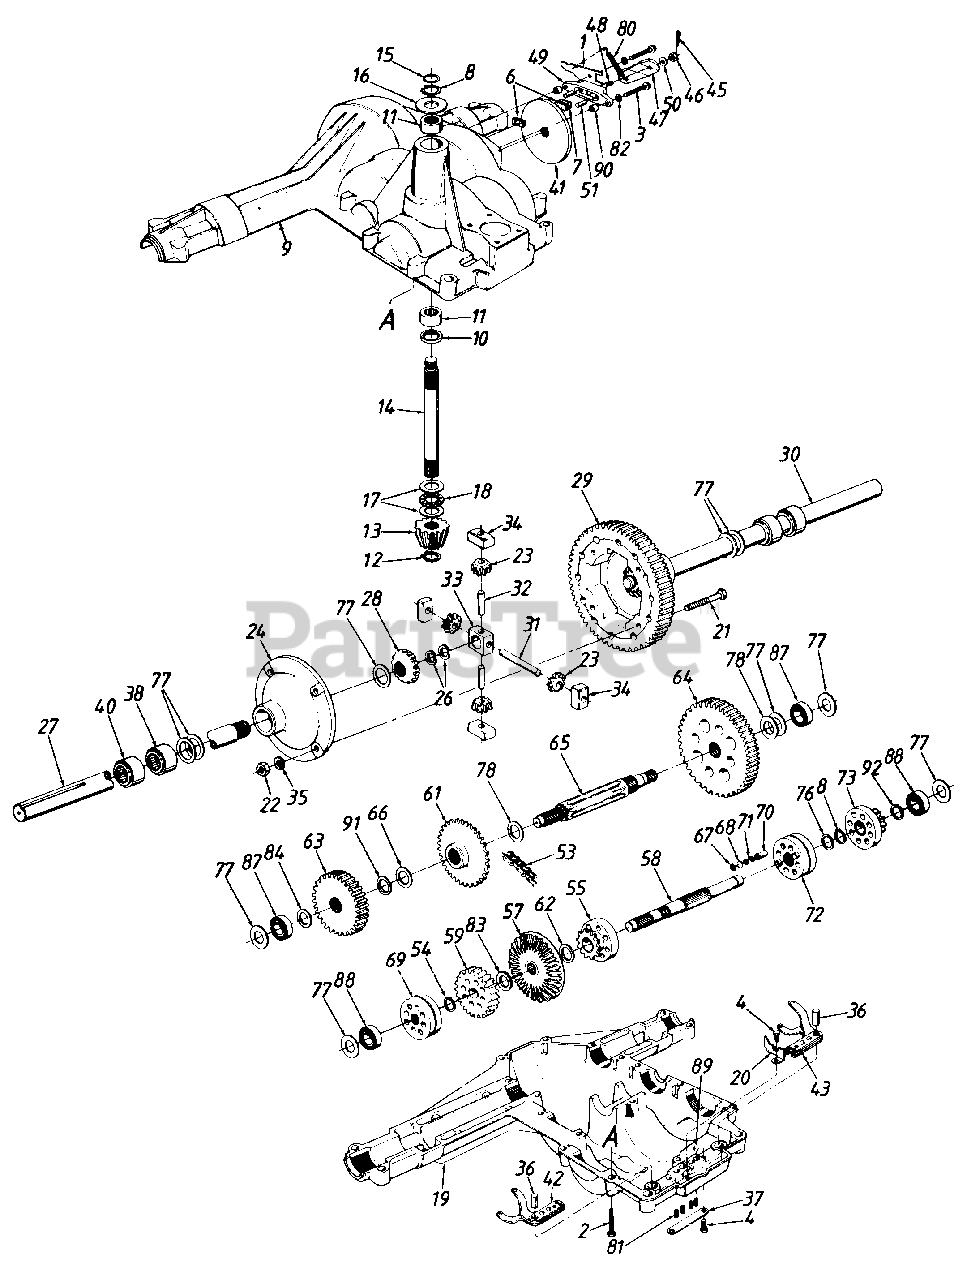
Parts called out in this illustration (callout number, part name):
1	Brake Return Bracket
2	Hex Bolt 1/4-20 x 1.25" Lg.
3	Hex Bolt 1/4-20 x 1.5" Lg. (Gr. 5)
4	Tap Scr. 1/4-20 x .38" Lg.
6	Brake Puck
7	Puck Plate
8	Retainer Ring
9	Upper Housing
11	Needle Brg. 518" I.D. x 718" O.D.
12	Snap Ring
13	Input Pinion 15T
16	Thrust Washer 518" I.D.
17	Thrust Washer
18	Thrust Bearing
19	Lower Housing
21	Hex Bolt 3/8-24 x 2.0" Lg.
22	Hex L-Nut 3/8-24 Thd. (Gr. 5)
23	Differential Gear 1OT
24	Differential Housing Cover Ass'y.
26	Retainer Ring
28	Differential Gear 14T
29	Differential Bull Gear 60T
32	Cross Shaft-Special
33	Differential Pinion Block
34	Differential Thrust Block
35	Spr. Wash. .39" I.D. x .62n O.D.
37	Spring Plate
38	Axle Bearing Ass'y.
40	Axle Bearing Ass'y.
41	Brake Disc
42	Shift Arm Ass'y.-R.H.
43	Shift Arm Ass'y.-L.H.
45	Cotter Pin 3/32" Dia.
46	Castle Nut 5/16-24 Thd.
47	Brake Actuating Arm
48	Sq. Hd. Bolt 5/16-24 Thd.
50	Fl-Wash. 11/32" I.D. x 718" O.D.
51	Brake Actuating Pin
53	#420 Chain 1/2 Pitch x 28 Links
54	Retainer Ring
55	Reverse Sprocket Ass'y.
57	Bevel Gear 47T
58	Drive Shaft
59	Spur Gear Ass'y.
61	Sprocket 22T
62	Fl-Wash. .81" l.D. x 1.18n O.D.
63	Spur Gear 31T
64	Spur Gear 45T
65	Output Shaft 9T
67	Internal Retainer Ring
68	Plug .44" Dia.
69	Forward Shift Collar
71	Drive Spring
72	Creeper Shift Collar
73	Creeper Collar Plate Ass'y.
76	Fl-Wash. .65" l.D. x .97" O.D.
77	Fl-Wash.
78	Fl-Wash. 1.0" l.D. x 1.56" O.D.
80	Ext. Spring 1.14" Lg.
81	Detent Spring
82	L-Wash. 1/4" l.D.
83	Fl-Wash. 5/8" I.D. x 1.0" O.D.
84	Fl-Wash. .68" x 1. 1 2n
87	Ball Brg. .669" I.D.
88	Ball Bearing
89	Ball Detent .25" Dia.
90	Spacer .254" l.D. x .5" O.D.
91	Fl-Wash. .69" l.D. x 1.06" O.D.
92	Fl-Wash.
